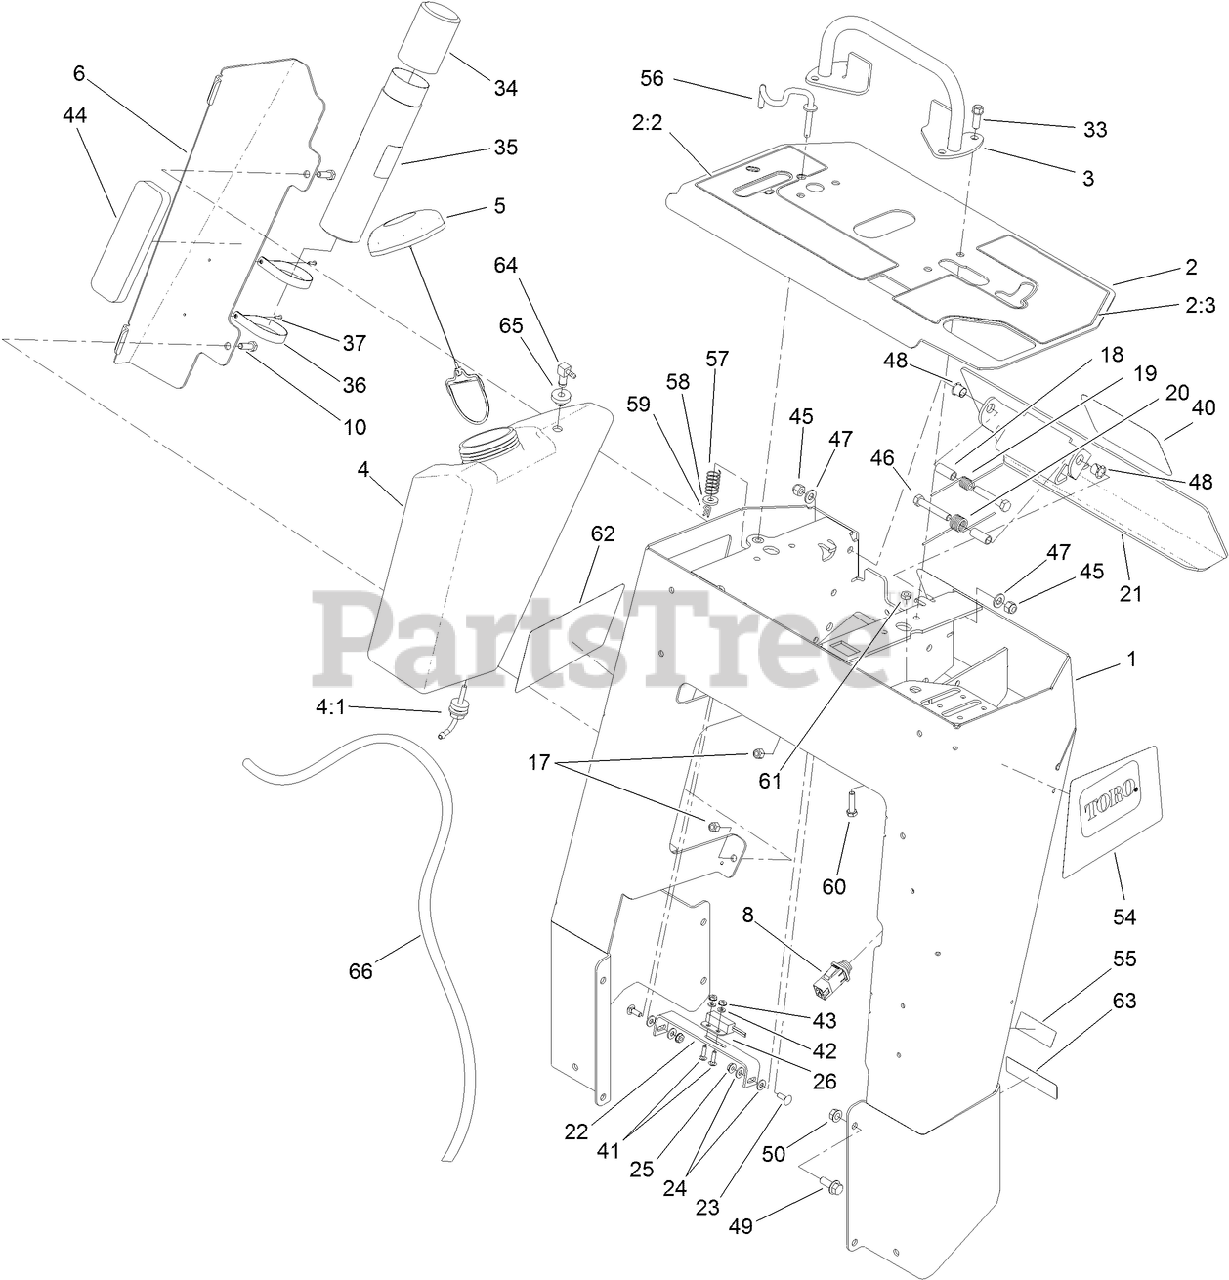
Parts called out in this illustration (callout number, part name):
2	PANEL-CONTROL
2:2	DECAL-CONSOLE, RH
2:3	DECAL-CONSOLE, LH
3	BAR-REFERENCE
4	TANK-FUEL
4:1	FITTING-FUEL, BULKHEAD
5	CAP-FUEL, RATCHETING
6	BRACKET-COVER, TANK
8	SWITCH-PLUNGER
10	SCREW-HH
17	NUT-LOCK, NI
18	SPACER-SPRING
19	SPRING-TORSION, LH
20	SPRING-TORSION, RH
21	PLATE-REVERSE
22	PLATE-SWITCH
23	BOLT-CARR
24	WASHER-FLAT
25	NUT-KEPS
26	SWITCH-PROXIMITY
33	SCREW-TAPTITE
34	CAP-HOUSING
35	TUBE-MANUAL
36	CLAMP-R
37	RIVET-POP
41	SCREW-CARR
42	WASHER-FLAT
43	NUT-KEPS
44	PAD-FOAM
45	NUT-LOCK, NI
46	SCREW-HH
47	WASHER-FLAT
48	BUSHING-NYLINER
49	SCREW-HHF
50	NUT-FLANGE
54	DECAL-SIDE, LH
55	DECAL-INFO
56	ROD-INTERLOCK
57	SPRING-CONTROL
58	WASHER-FLAT
59	PIN-COTTER
60	SCREW-HH
61	NUT-JAM
62	DECAL-SIDE, RH
63	DECAL-ARRESTER, SPARK
64	FITTING-ELBOW, 90 DEG
65	BUSHING
66	HOSE-VENT, TANK
